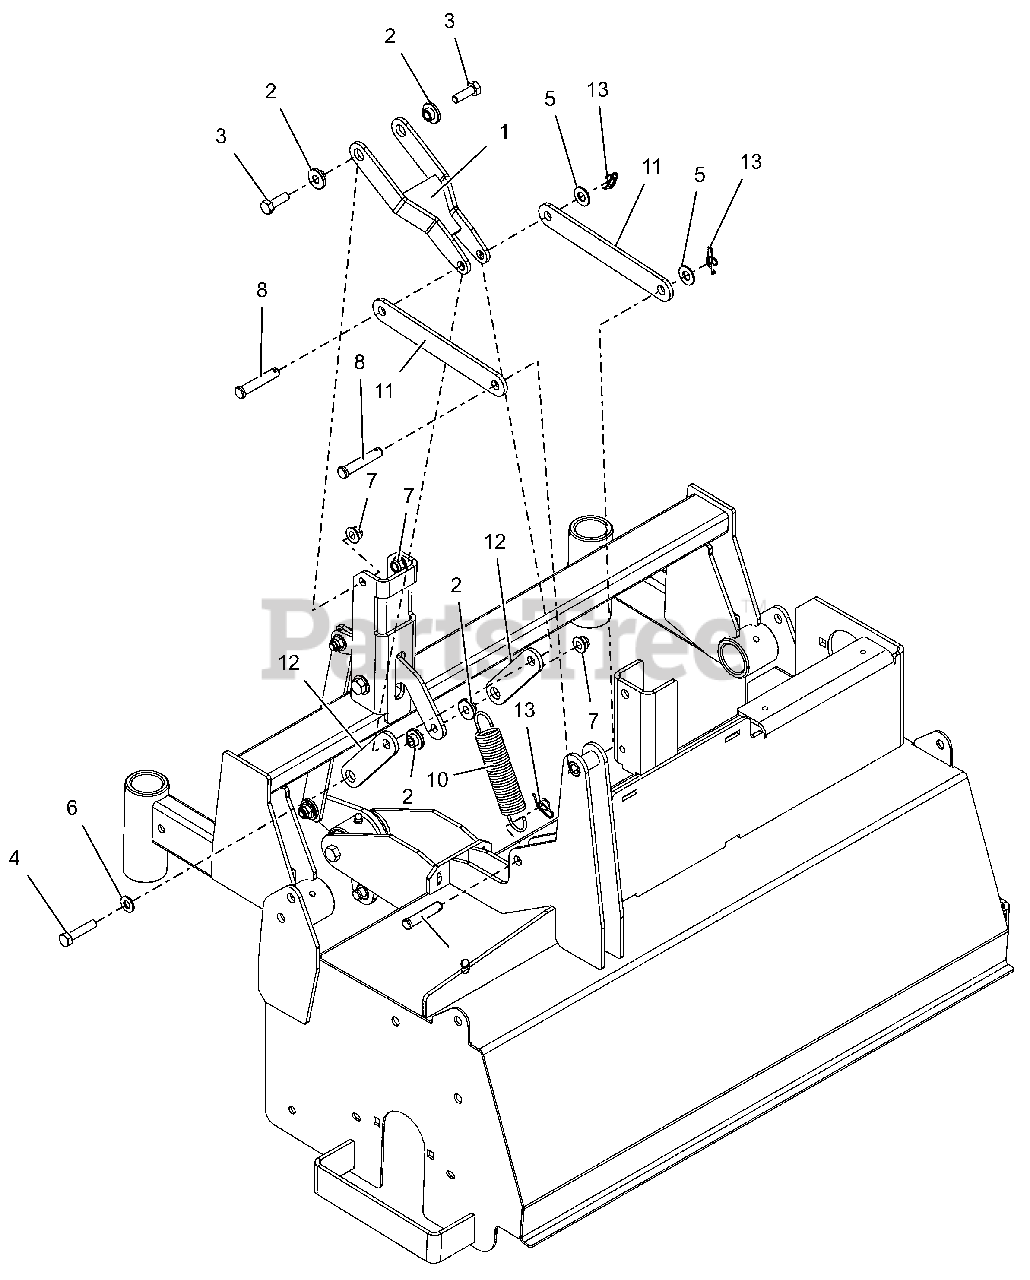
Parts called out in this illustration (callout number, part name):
1	WLDMT, CONTROL HEIGHT
2	BSHG-FLG .32X.500X.344X.880
3	BLT,HEX .31-18X1.00 G5 ZCC
4	BLT, HEX .31-18X1.50 G5 ZCC
5	WSHR,FLT .406X.812X.065 ZCC
6	WSHR,FLT .344X.688X.065 ZCC
7	NUT,NYL-FLG .31-18 GF ZCC
8	PIN, CLEVIS
9	PIN-CLEV .370X1.75
10	SG-TENS .105X1.00X5.0
11	ARM, LINK
12	PLT, LINK - BLACK
13	RING, RUE .375 X .054 X 1.254
